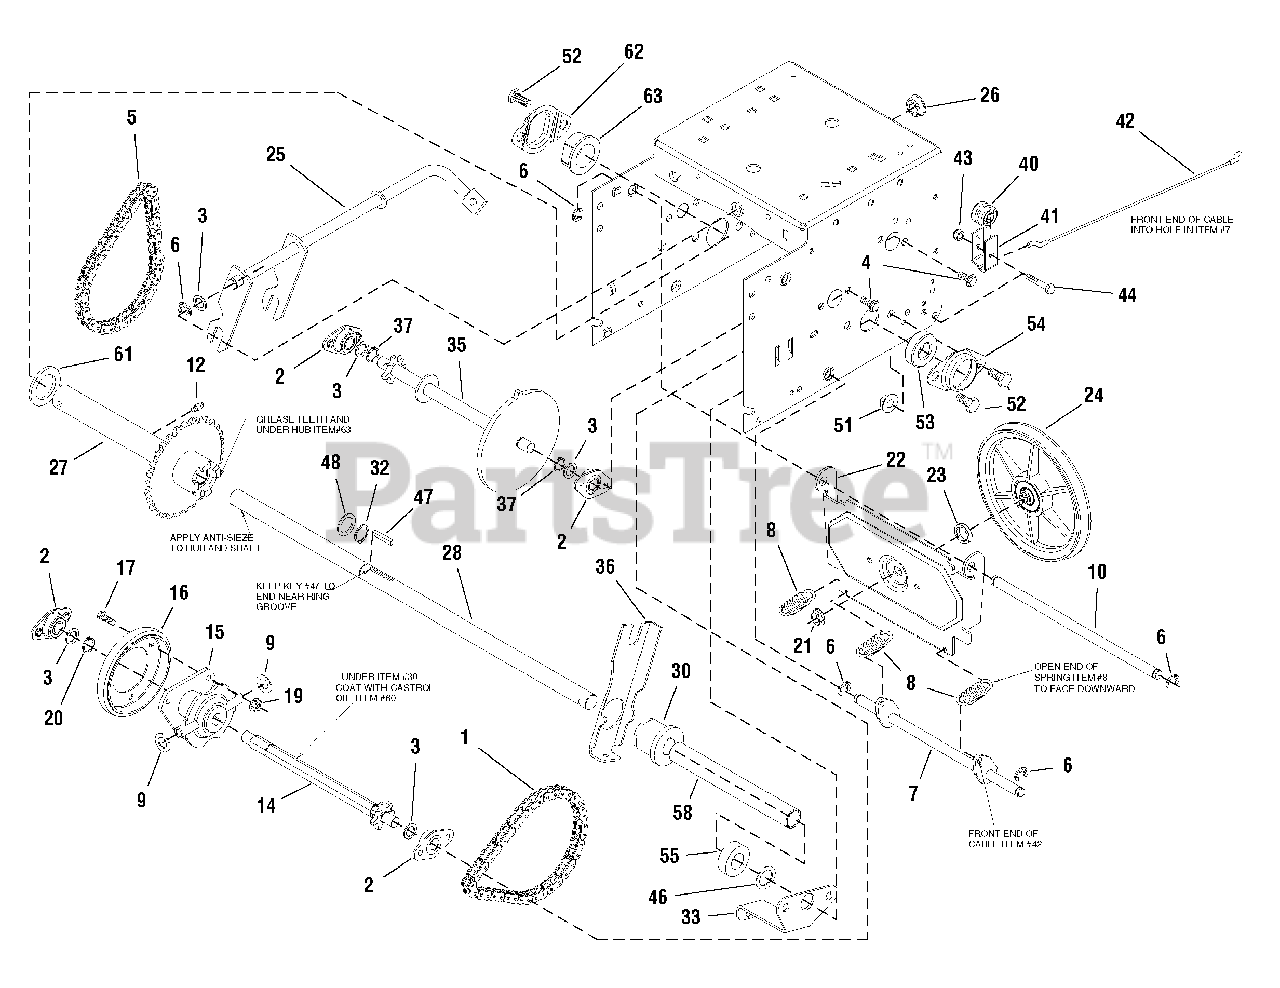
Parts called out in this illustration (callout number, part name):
1	CHAIN, Roller
2	RETAINER & BUSHING ASSEMBLY
3	WASHER
4	SCREW, Hex Washer Head Taptite 5/16-18 x 1/2
5	CHAIN, Roller
6	RETAINER, Ring 7/16
7	SPRING LINK ASSEMBLY
8	SPRING, Extension
9	WASHER, 1/2
10	AXLE, Swing Plate
12	FITTING, Lube
14	HEX SHAFT & SPROCKET ASSEMBLY
15	HUB, Friction Wheel & Bearing
16	WHEEL, Friction
17	CAPSCREW, Hex Head 1/4-20 x 5/8 G5
19	NUT, Hex KEPS 1/4-20
20	RING, Retaining Extension
21	NUT, 3/8-24 Flange Lock
22	PLATE, Swinging
23	SPACER, Friction Pulley
24	FRICTION PULLEY ASSEMBLY
25	SPEED SELECT ASSEMBLY
26	BEARING, Flange
27	SPROCKET & HUB ASSEMBLY, W/Bushings
28	AXLE
30	GEAR, Clutching Powedered Metal
32	RING, Retaining Extension
35	SPROCKET & SHAFT ASSEMBLY
37	RING, Retaining Extension
40	SPOOL CABLE, Auger Control
41	BRACKET, Cable Spool
42	CABLE, Front Drive Lower All
43	NUT, Hex Lock ESNA Light 1/4-20
44	CAPSCREW, Hex Head 1/4-20 x 1-1/2 G5
46	WASHER, Flat
48	WASHER, 3/4
51	NUT, Hex Flange 3/8-16 Whiz Lock
52	CAPSCREW, Hex Head 3/8-16 x 3/4 G5
53	BEARING, Ball
54	RETAINER, Bearing
55	COLLAR, Locking
58	SPRING, Compression
0060	WASHER, Spring, 0.475
61	WASHER, 1-3/16
62	RETAINER, Bushing
63	BUSHING, Plastic
0140	SCREW, Washer Head Taptite, 5/16-18 X 3/4
0170	SUPPORT, Idler Arm
